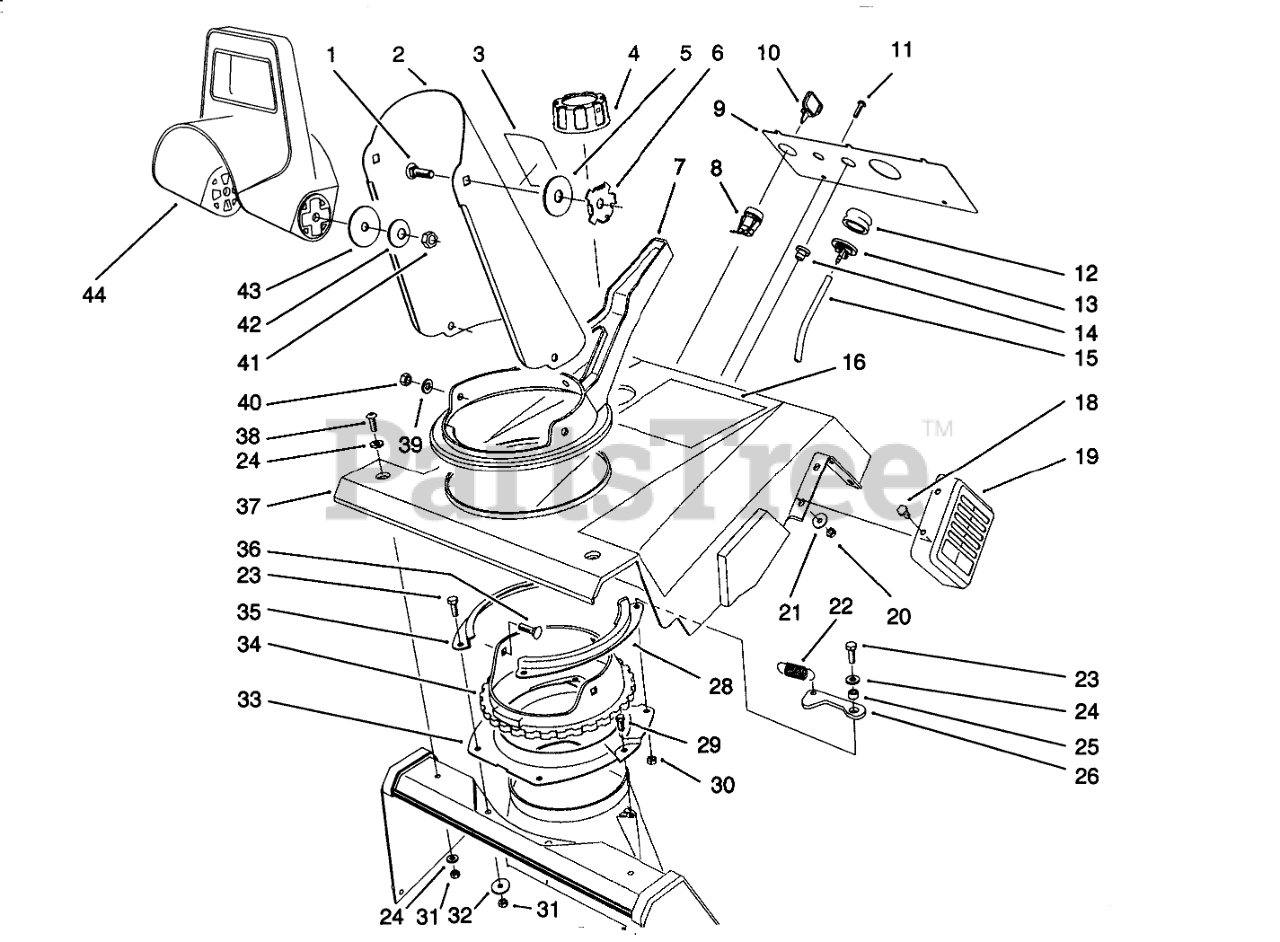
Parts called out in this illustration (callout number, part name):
1	SCREW-CARR
2	Discharge Chute Assembly (Incl. Ref. #3) (Model No. 38195)
3	DECAL-DANGER DISCH.
4	CAP-FUEL ASM
5	WASHER-RUBBER
6	PLATE-FRICTION
7	CHUTE - HANDLE
8	SWITCH
9	CNTRL PANEL/SILK SCREEN
10	KEY-IGNITION
11	SCREW-SHWH, THREAD FORMING
12	BULB-PRIMER
13	BODY-PRIMER
14	GUIDE-ROPE, STARTER
15	HOSE-PRIMER
16	DECAL - CCR 1000E
18	SCREW-HWH
19	Guard-Muffler
20	NUT-LOCK, NI
21	WASHER-FLAT
22	SPRING-EXTENSION
23	SCREW-HH
24	WASHER-FLAT
25	SPACER-BLADE, ROTOR
26	DETENT
28	Retainer-Chute Ring
29	SCREW-PLASTITE
30	NUT-LOCK, NI
31	NUT-LOCK, NI
32	WASHER-FLAT
33	Ring-Chute Support
34	GEAR RING, CHUTE
35	Retainer-Chute Ring
36	SCREW-CARR
37	UPPER SHROUD
38	SCREW-PPH
39	WASHER-FLAT
40	NUT-KEPS
41	NUT-LOCK, NI
42	WASHER-BELLEVILLE
43	WASHER-FLAT
44	CHUTE-DEFLECTOR
